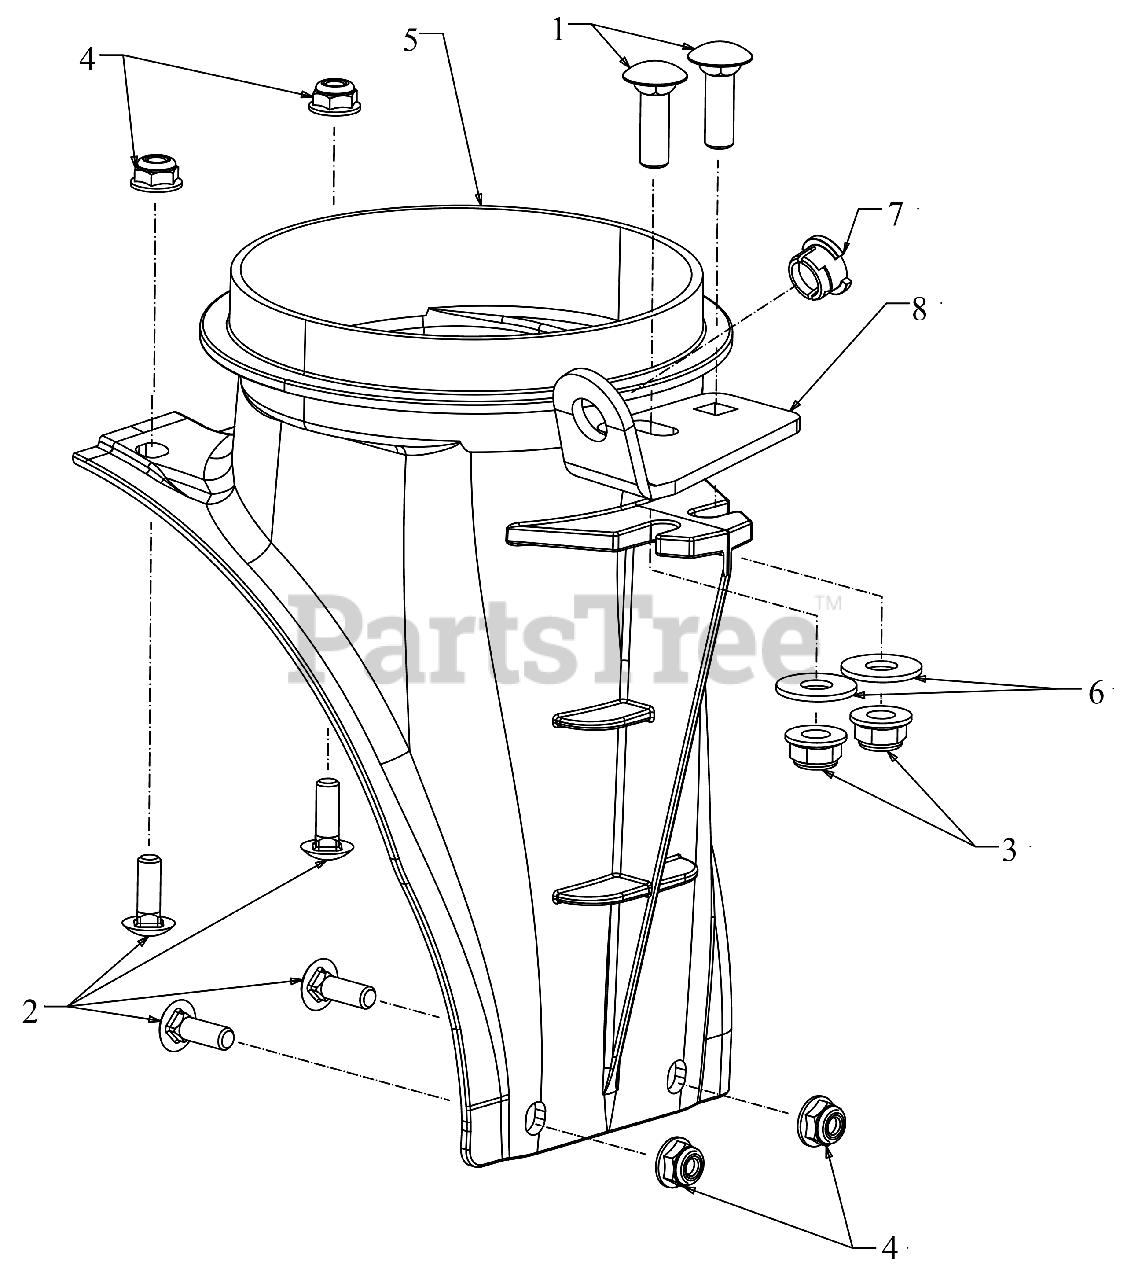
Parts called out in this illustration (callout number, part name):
1	CARRIAGE BOLT 5/16-18 x 1.00
2	SCREW 1/4-20 x .75 GR5
3	FLANGE LOCK NUT 5/16-18
4	FLANGE LOCK NUT
5	CHUTE ADAPTER
6	FLAT WASHER
7	BUSHING .380 ID
8	CHUTE CRANK BRACKET
